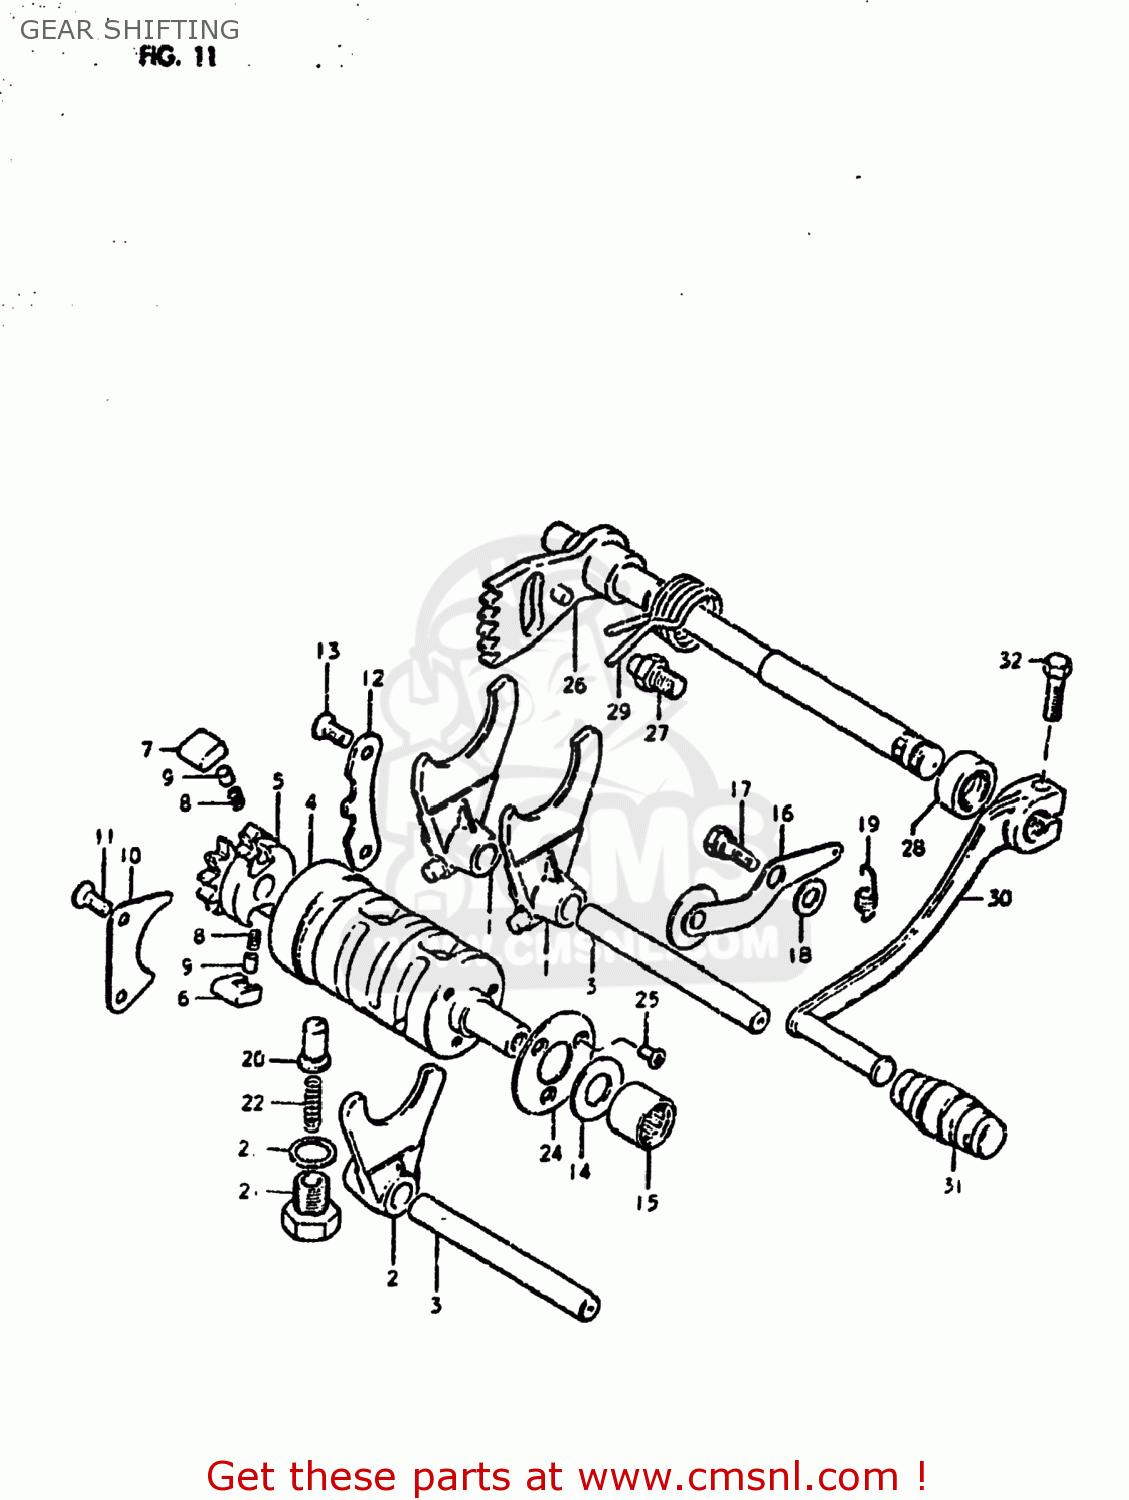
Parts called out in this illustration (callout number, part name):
1	FORK,GEAR SHIFT NO.1
2	FORK,GEAR SHIFT NO.3
3	SHAFT,GEAR SHIFT FORK
4	CAM,GEAR SHIFT
5	RETAINER,GEAR SHIFT CAM
6	PAWL,GEAR SHIFT NO.1
7	PAWL,GEAR SHIFT NO.2
8	SPRING
9	PIN(5X8)
10	LIFTER,GEAR SHIFT PAWL
11	SCREW
12	GUIDE,GEAR SHIFTING CABLE
13	SCREW
14	WASHER
15	ROLLER BEARING (12X18X1
16	STOPPER,GEAR SHIFTING
17	BOLT(6X16.1)
18	WASHER
19	SPRING
20	STOPPER,GEAR SHIFT CAM NO.2
21	HOLDER,GEAR SHIFT CAM STOP SPR
22	SPRING
23	GASKET(14X19.2X2) (NAS)
24	PLATE,GEAR SHIFT CAM STOPPER
25	SCREW 4X12
26	27
27	STOPPER,GEAR SHIFT CAM
28	OIL SEAL
29	SPRING
30	LEVER ASSY,GEAR SHIFT
31	RUBBER,GEAR SHIFT PEDAL
32	BOLT
